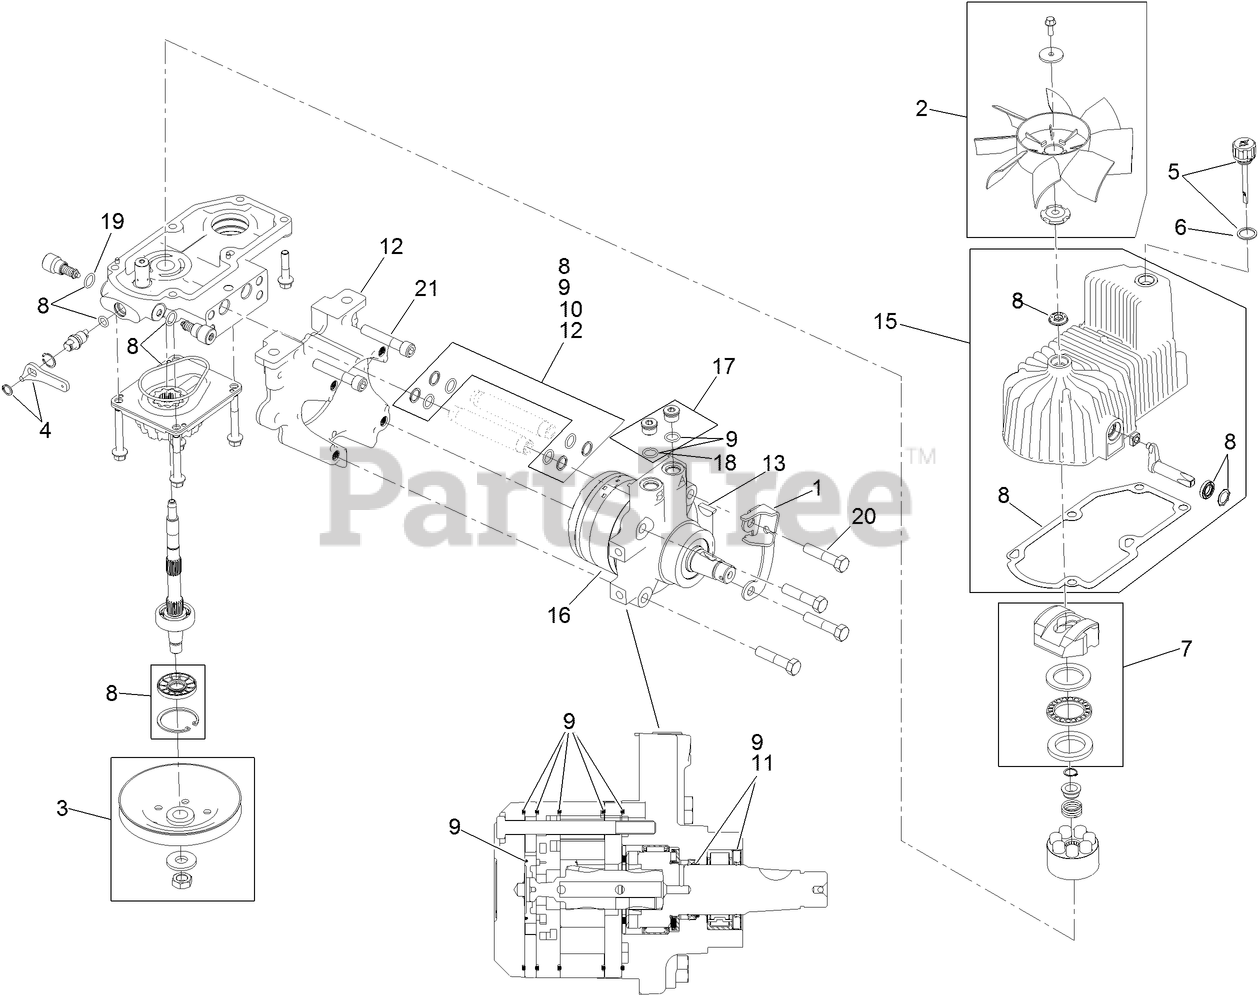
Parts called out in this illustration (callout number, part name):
1	BRACKET-ANCHOR, CABLE
2	FAN KIT
3	PULLEY KIT
4	HANDLE-BYPASS VALVE, HYDRO
5	DIPSTICK-HYDRO W/GASKET
6	GASKET-DIPSTICK, HYDRO
7	SWASH BLOCK KIT
8	PUMP SEAL KIT
9	MOTOR SEAL KIT
10	TUBE SEAL KIT
11	OUTPUT SHAFT SEAL KIT
12	NOSE CUP-UHT
13	KEY-WOODRUFF
15	Housing-RH
16	MOTOR-HYDRAULIC, RH 280CC
17	MAGNETIC PLUGS SERVICE KIT
18	O-RING
19	O-RING-CHECK VALVE
20	SCREW HH
21	SCREW-HSH
